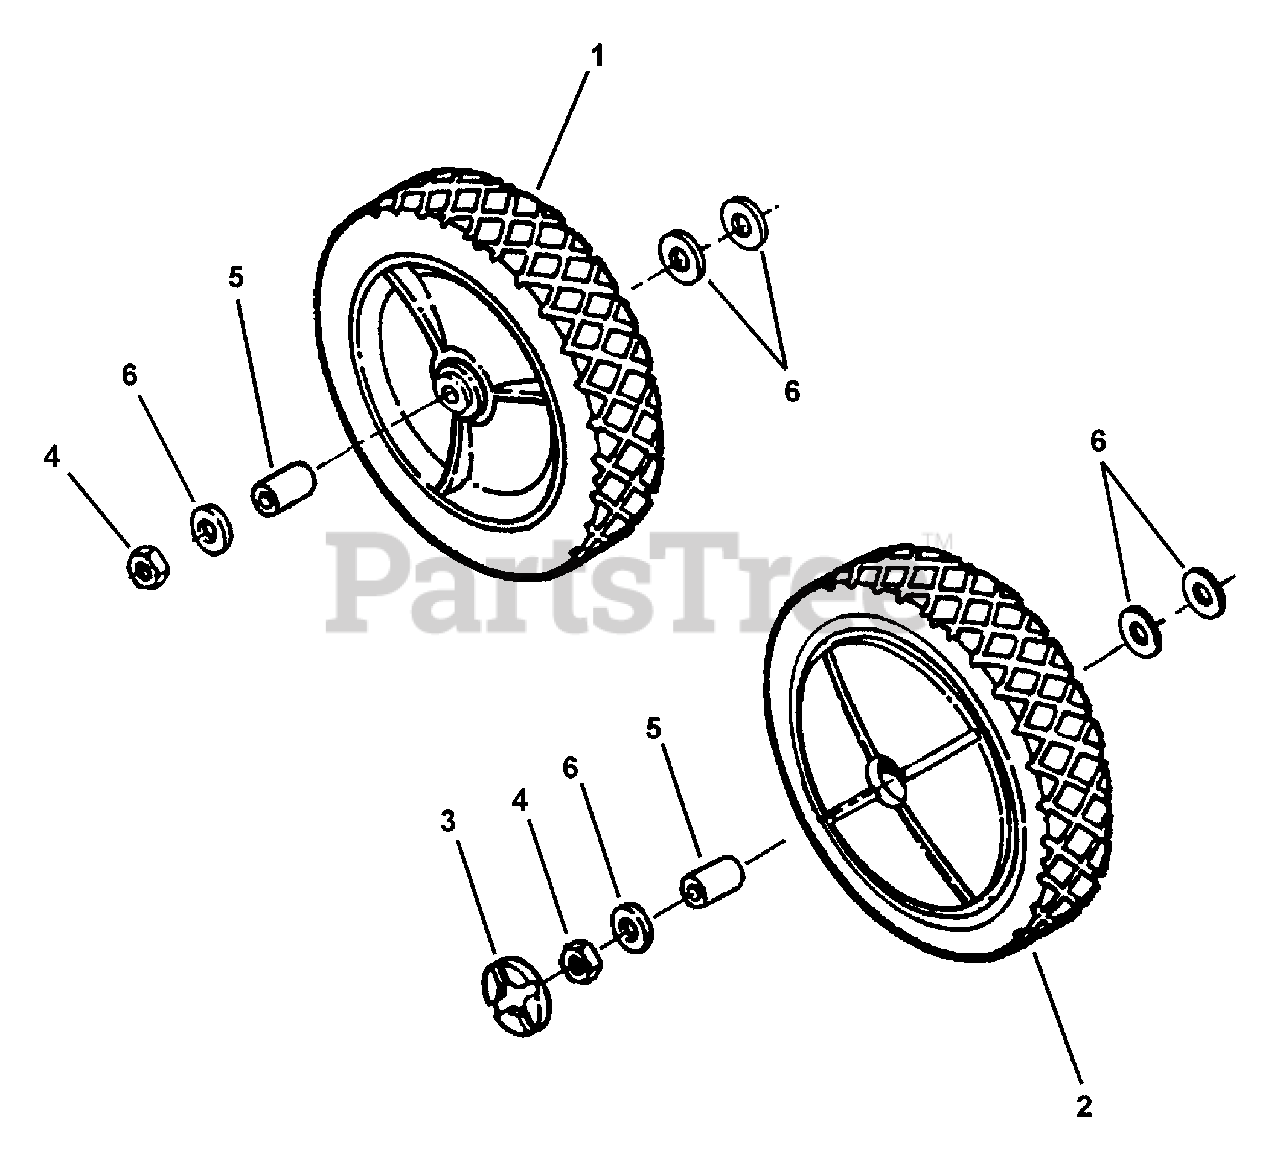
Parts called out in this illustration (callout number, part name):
1	WHEEL, 8 x 1.75 Plastic
2	WHEEL, 8 x 1.75 Plastic
3	PLUG, Wheel
4	NUT, 7/16-20 Hex (Thin)
5	BUSHING, Axle
6	WASHER, 7/16 x 1" O.D. Flat
